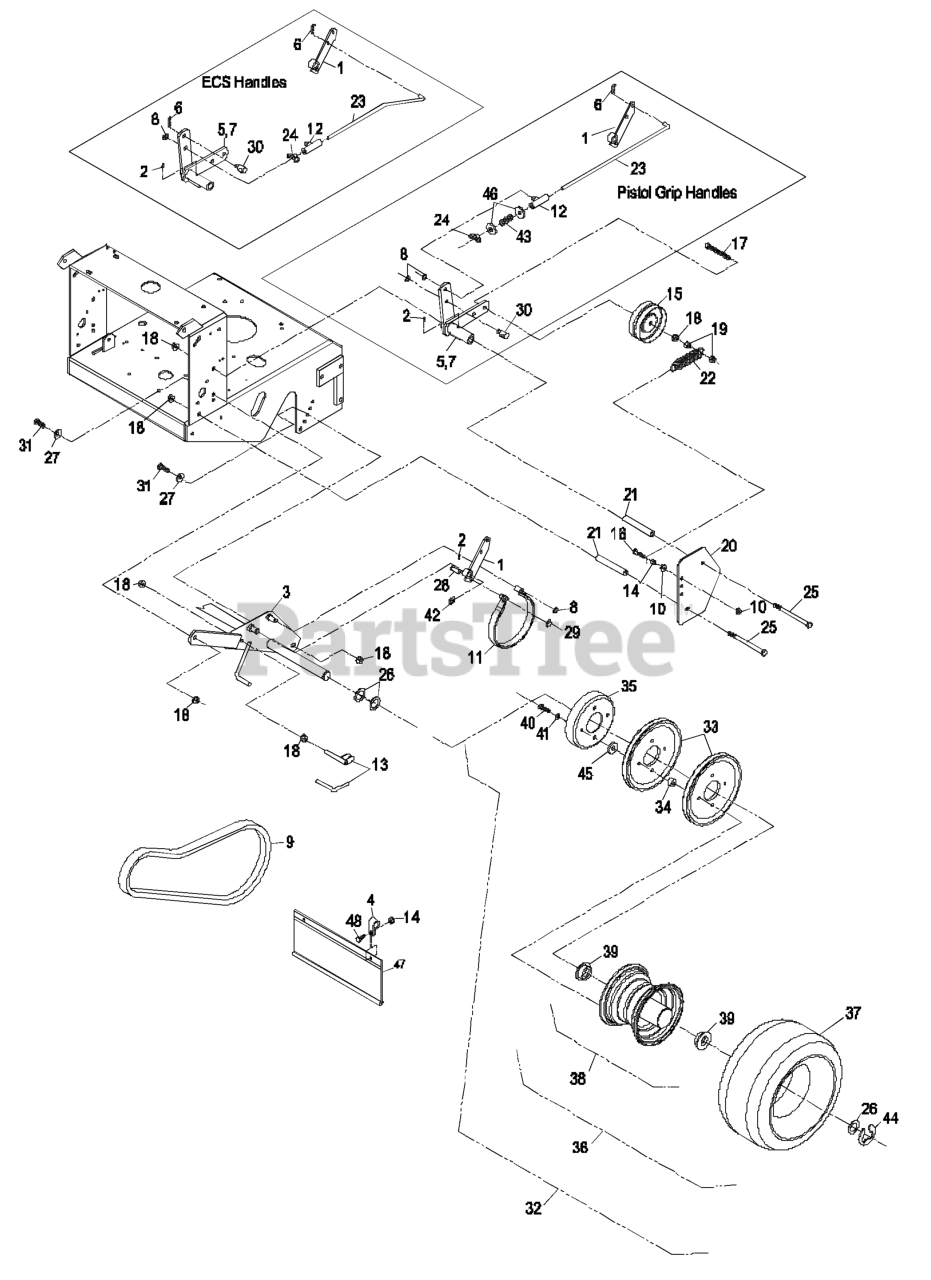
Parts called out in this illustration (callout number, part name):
1	ARM-BRAKE
2	FITTING-GREASE
4	CLAMP-R
6	PIN-COTTER
8	RING-RETAINING
9	BELT,WHEEL DRIVE
11	BAND-BRAKE
13	SCRAPER
14	NUT-LOCK, NI
15	IDLER-WHEEL, DRIVE
16	SCREW-HH
17	SCREW-HH
18	NUT-HHF, WHIZ
19	NUT-LOCK, NI
20	SHIELD-WHEEL, DRIVE
21	SPACER-SHIELD
22	SPRING-EXTENSION
23	LINKAGE-BRAKE
24	WINGNUT-NYLOCK
25	SCREW-HH
26	WASHER-SPACER
27	WASHER-BELLEVILLE
28	PIN-CLEVIS
29	RING-RETAIN,PUSH,EXT,FLAT
30	SWIVEL-LEVER, DRIVE
31	SCREW-HH
33	SHEAVE-WHEEL, DRIVE
34	SPACER-SHEAVE, WHEEL
35	DRUM-BRAKE
36	WHEEL AND TIRE ASM
37	TIRE-TURFMASTER
38	WHEEL AND HUB ASM
39	BEARING-FLANGED
40	SCREW-HH
41	WASHER-LOCK
42	RING-RETAINING, EXTERNAL
43	SPRING-COMPRESSION
44	RING-SNAP
46	WASHER-PLAIN
47	SHIELD-TRAILING
48	SCREW-HH
